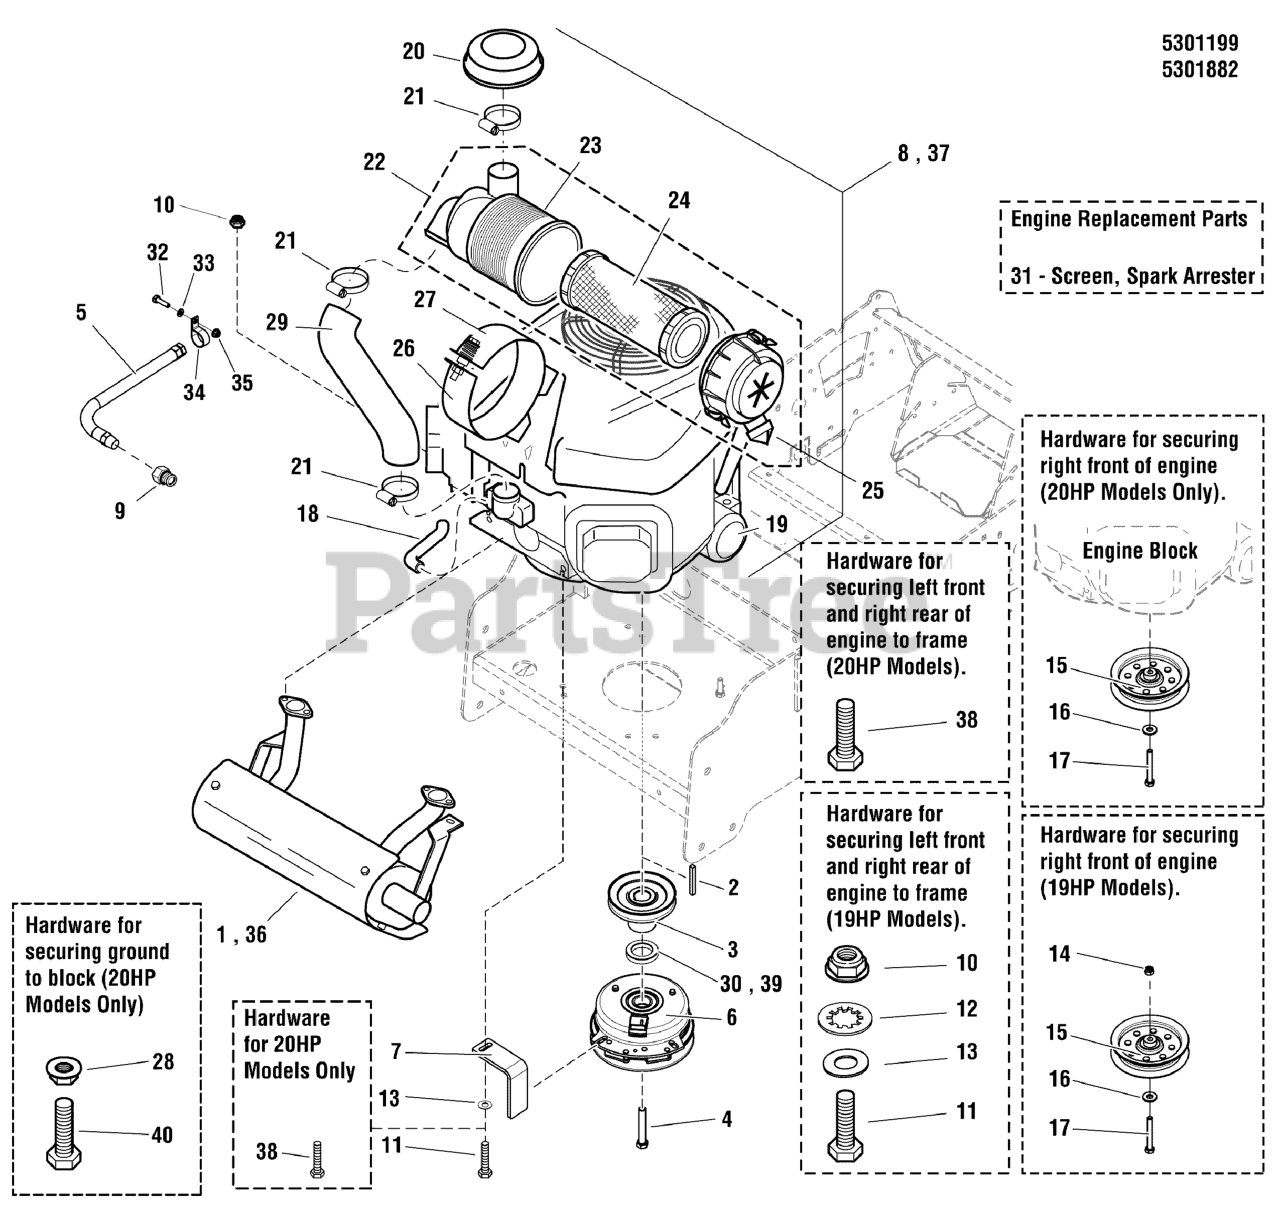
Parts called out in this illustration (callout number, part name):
1	MUFFLER, 19HP KAWASAKI
2	KEY, 1/4 SQ X 1
3	PULLEY, PUMP DRIVE, 4.857 OB X 1-1/8
4	BOLT, CRANKSHAFT, 7/16"X2-1/2
5	HOSE, OIL DRAIN
6	* CLUTCH, 5218-134, WARNER
7	ANCHOR, CLUTCH - BLK
9	ADAPTER, OIL DRAIN
10	NUT, 5/16-18 HEX NYLON LOCK
11	BOLT, 5/16-18 X 1-3/4 GD5 YZ
12	WASHER, 5/16" INT. TOOTH LOCK
13	WASHER, 5/16" SAE
14	SEE PUMP DRIVE GROUP
15	SEE PUMP DRIVE GROUP
16	SEE PUMP DRIVE GROUP
17	SEE PUMP DRIVE GROUP
18	BREATHER TUBE
20	RAIN COVER
22	AIR FILTER ASSEMBLY
23	CASE, AIR FILTER
24	AIR FILTER, PRIMARY
26	CASE, BRACKET, AIR FILTER
27	CASE, BRACKET, AIR FILTER
28	NUT, M8-1.25 SERR FLANGE, CZ
29	AIR INLET TUBE
30	SPACER, 1.13 X 1.75 X .32
32	BOLT, 1/4-20 X 1" GD5 CZ
33	WASHER, 1/4 SAE
34	CLAMP, VINYL INSULATED
35	NUT, 1/4-20 HEX NYLOCK FLANGE
36	MUFFLER, (16-20HP), KAWASAKI S50X
38	BOLT,HEX FLG,SER GD5 3/8-16X1-1/4PACH CZ
39	SPACER, 1.13 X 1.75 X .62
40	BOLT, M8-1.25 X 20 MM GD 8.8
